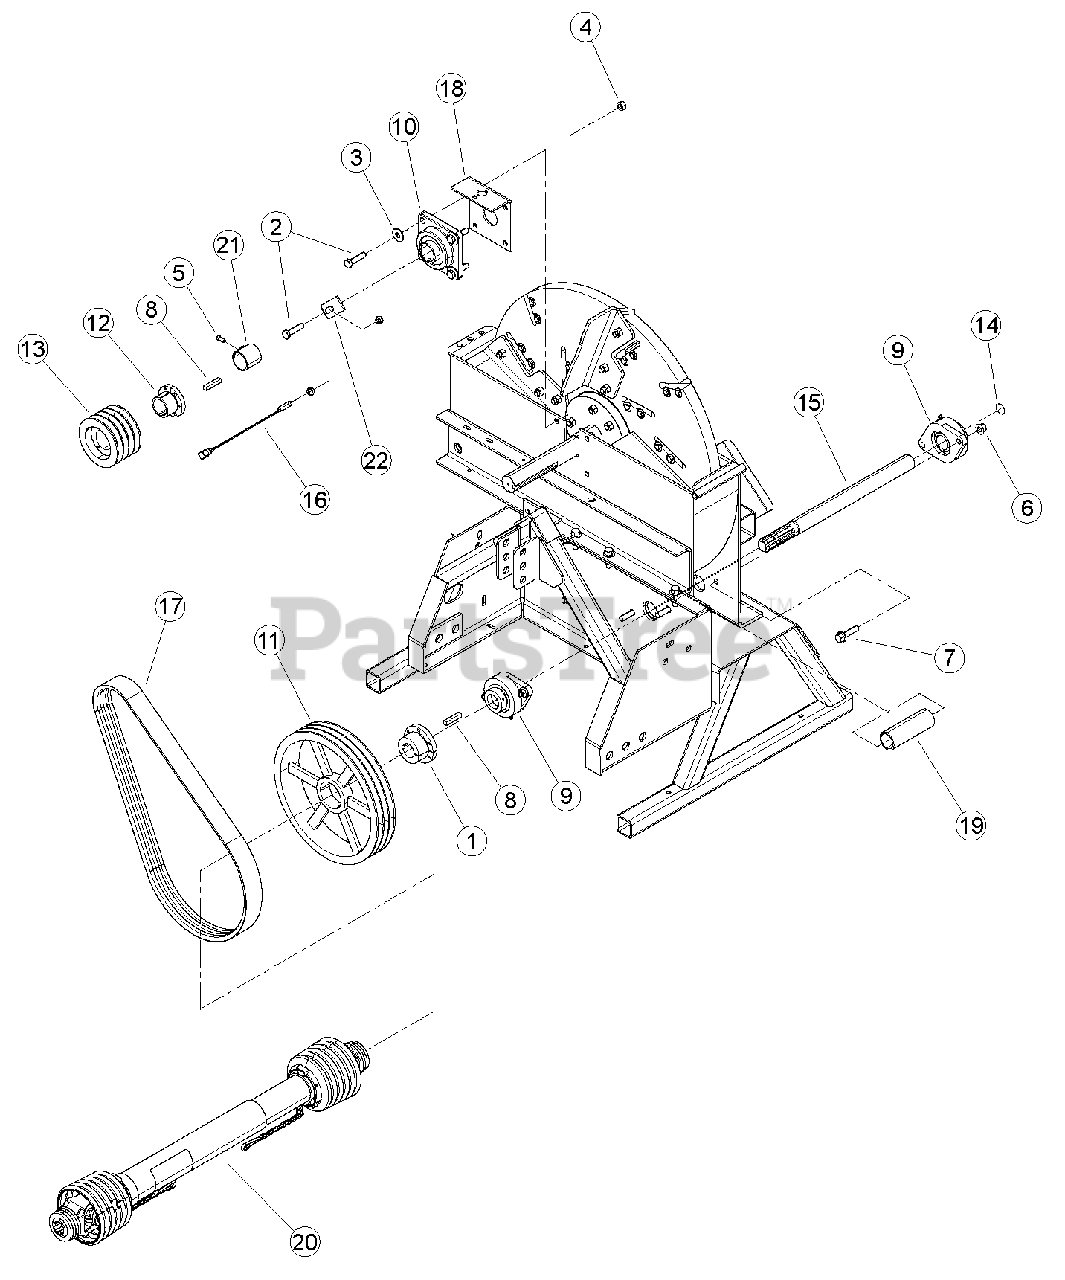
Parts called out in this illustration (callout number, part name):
1	BUSHING, SK 1-1/2"
2	BOLT, 1/2 X 2 GR5 HEX CAPSCREW ZP
3	WASHER, 1/2" FLAT ZP
4	NUT, 1/2" CENTERLOCK GRB ZP
5	SCREW, 5/16-18 X 5/8 SQ HD SET
6	NUT, 1/2-13 NYLOCK FLANGE
7	BOLT, 1/2-13 X 2 HWH GR5 CZP
8	KEY, 3/8" SQ X 2" LG PLAIN
9	BEARING, 2 BOLT FLANGE 1-1/2" BORE
10	BEARING, 1-3/4 4 BOLT FLANGE
11	SHEAVE, 3B13.6 SK
12	BUSHING, SD 1-3/4"
13	SHEAVE, 4BQ4.8 SD
14	DECAL, ROTATING SHAFT
15	SHAFT, 6 SPLINE INPUT
16	SENSOR, M12 PNP PROXIMITY (REPLACEMENT PART)
17	BELT, 3RB64
18	WELDMENT, LEFT BEARING BRACKET
19	SHIELD, SHAFT
20	ASSEMBLY, 8" & 9" PTO DRIVELINE
21	WELDMENT, SPACER
22	BRACKET, SENSOR SHORT MOUNT
